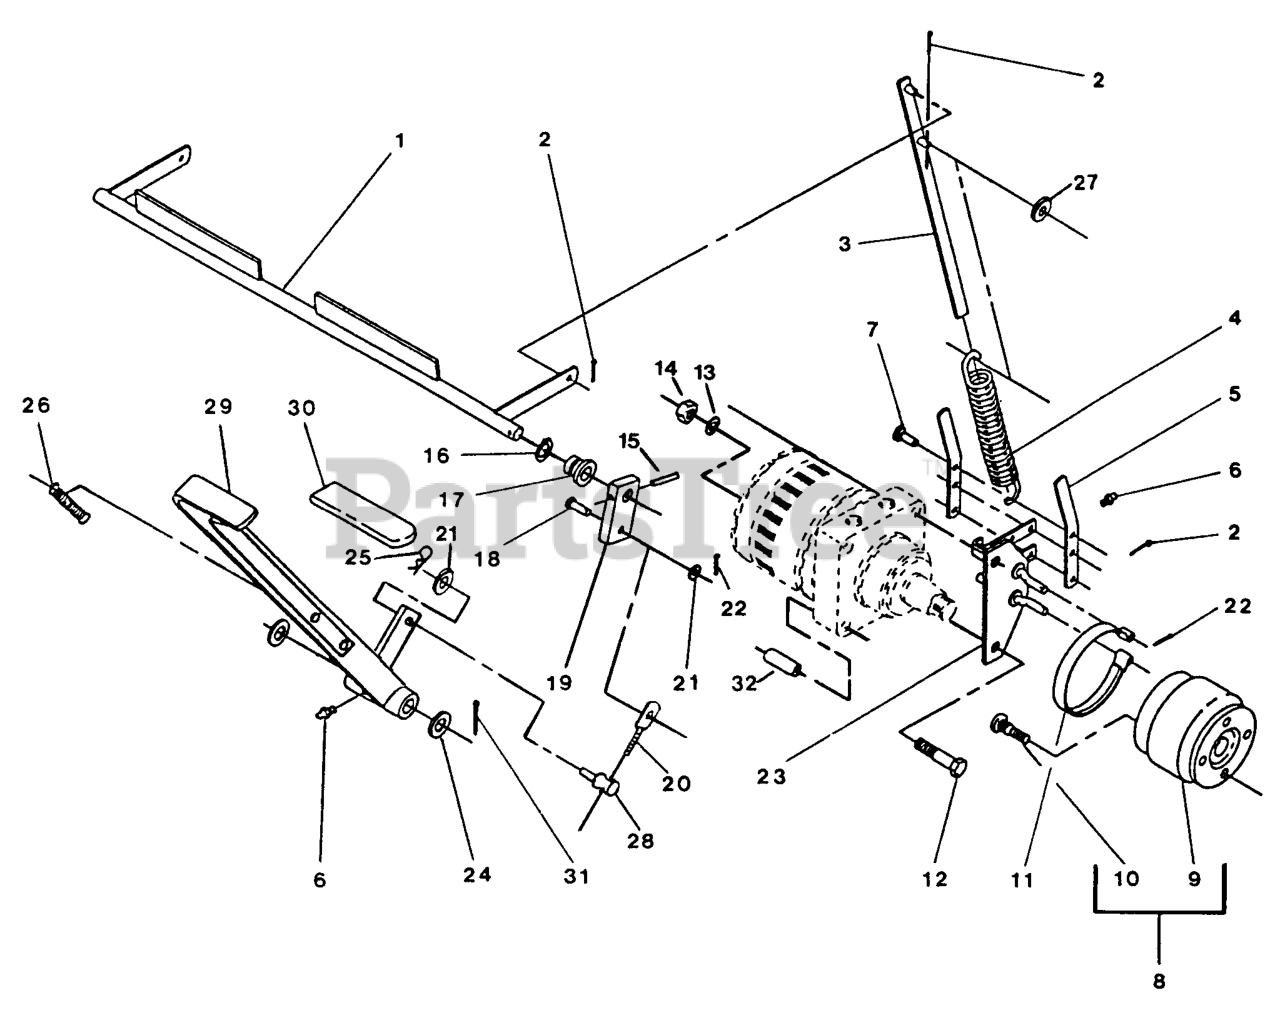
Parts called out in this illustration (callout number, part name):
1	WLD,ROD LOCKOUT
4	SPRING,EXTENSION
5	LINK,BRAKE CONNECTING
8	HUB/BRAKE DRUM ASSY
10	BOLT,HUB
11	BAND,BRAKE
18	PIN-CLEVIS
23	BRAKE BRKTW/ZERK LH
25	PIN-COTTER
26	SPRING,BRAKE HANDLE
29	HANDLE & TRIGGER, BRAKE
30	GRIP-LEVER
32	SPACER,MOTOR MOUNTING
